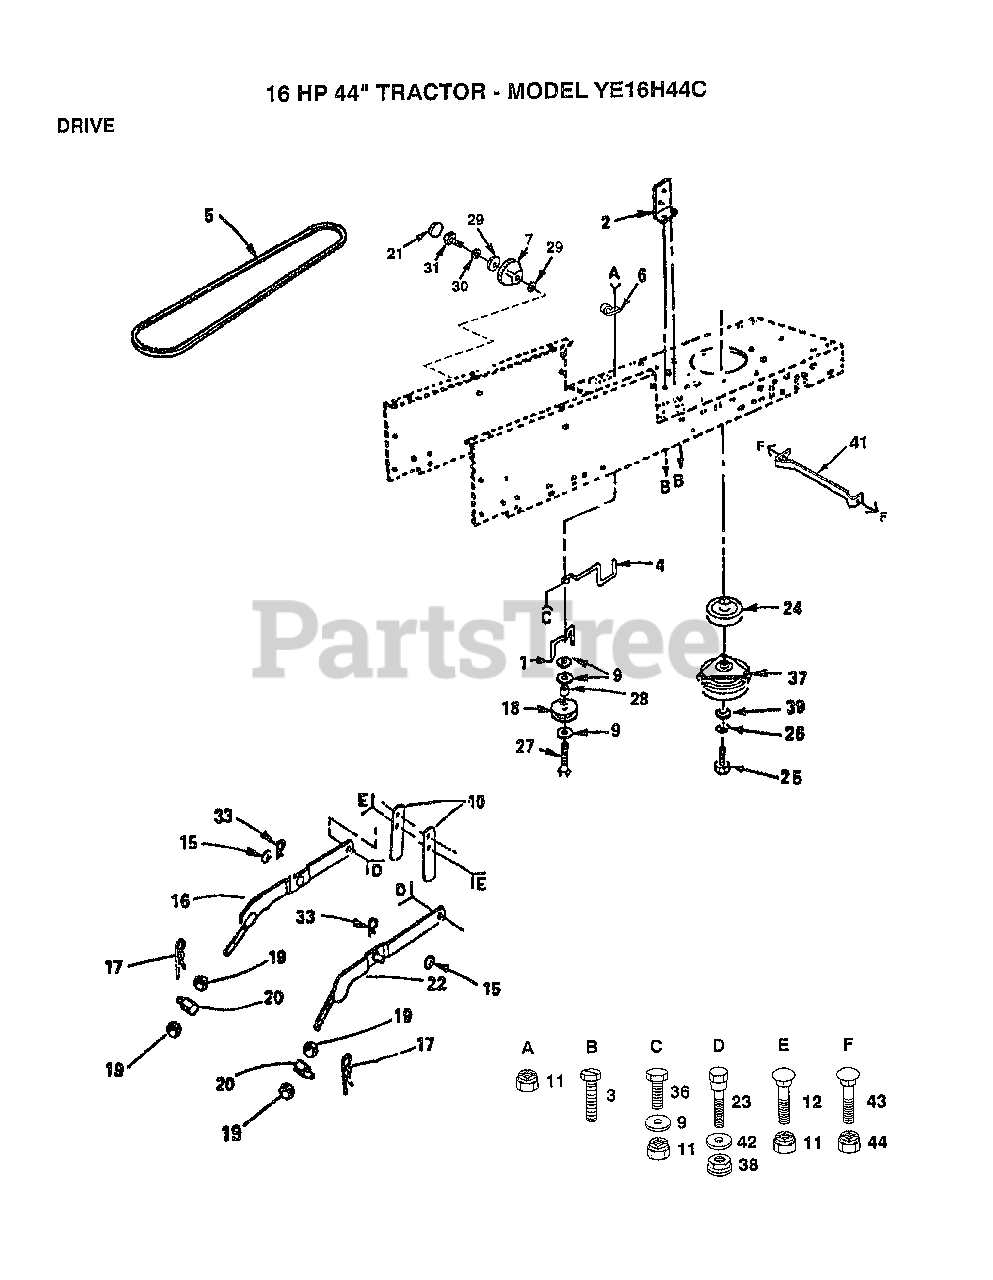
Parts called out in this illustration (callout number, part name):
1	BELT KEEPER LT
2	BRACKET LT
3	SCREW
6	CLIP T
7	HEIGHT INDICATOR
9	WASHER
10	UPSTOP
16	LH SUSP ARM ASM
17	SPRING H
18	PULLEY.IDLER.FLAT
19	NUT
21	"PLUG,HOLE"
22	RH SUSP ARM ASM
23	"BOLT, SHOULDER LT"
26	LOCKWASHER
27	BOLT
28	SPACER T
29	WASHER
30	LOCKWASHER
33	SPRING.RETAINER
36	BOLT
38	NUT SPECIAL T
39	WASHER
42	WASHER T
43	BOLT
